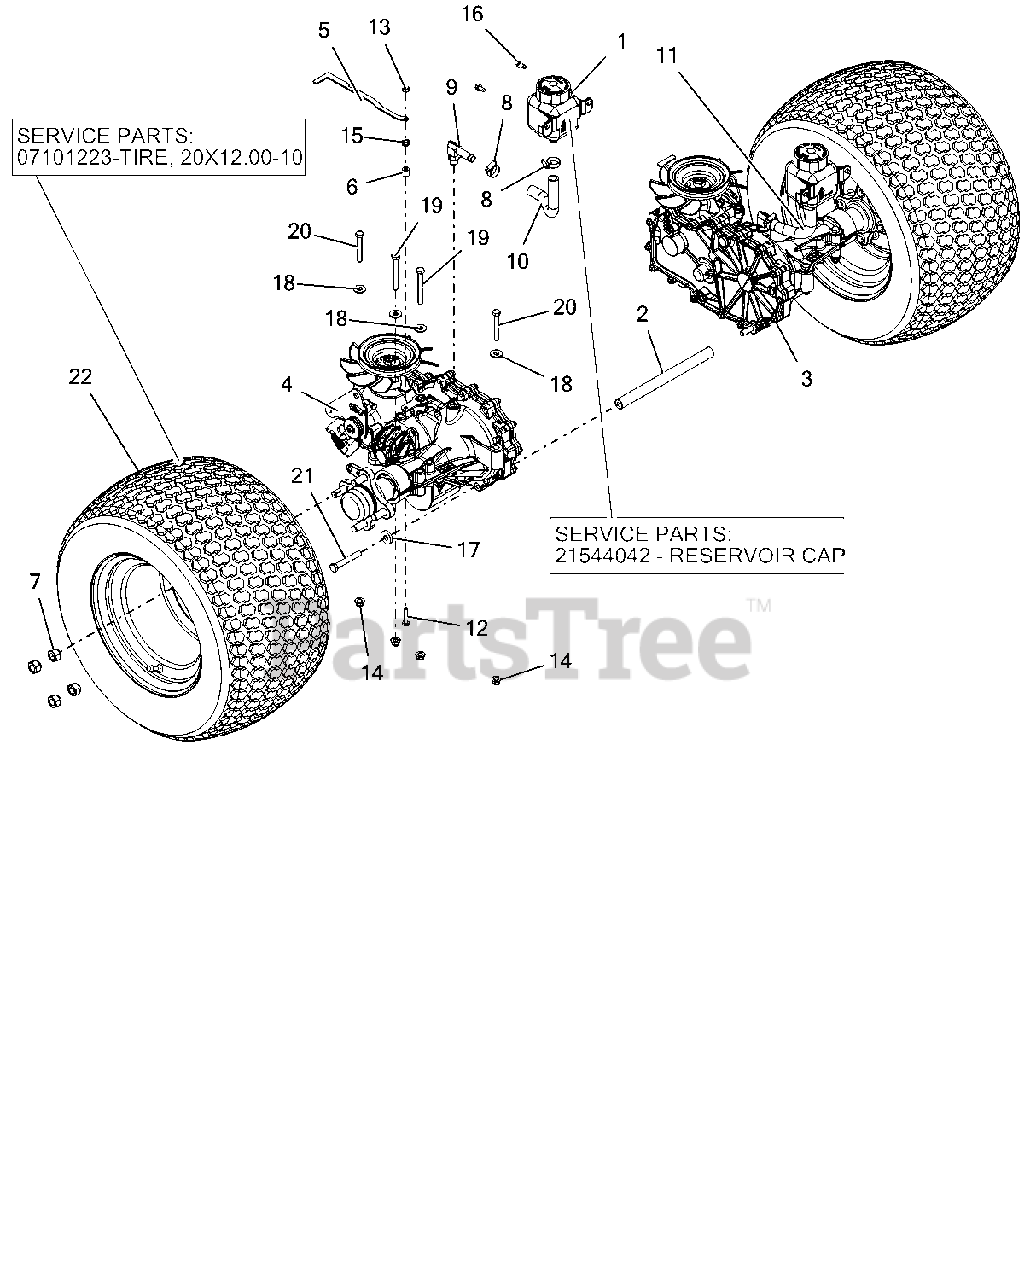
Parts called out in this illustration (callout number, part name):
1	TANK, EXPANSION ZT2800
1	RESERVIOR CAP
2	ROD, TRANSAXLE BRACE-9.27 (BLACK)
3	TRANSAXLE, ZT2800 - LH
4	TRANSAXLE, ZT2800 - RH
5	BRKT, VALVE DUMP -XL
6	BSHG, SLV .265X.500X.500
7	NUT, LUG .500-13
8	CLAMP, .88 DIA HOSE
9	FITTING, HYD (90 DEG)
10	HOSE, EXPANSION TANK-FORMED RH
11	HOSE, EXPANSION TANK-FORMED LH
12	BLT-HEX .25-20X1.25 GR5 YWZC
13	NUT-LK-CTR-JAM .25-20 YWZC
14	NUT-LK-NYL-FLG .31-18 YWZC
15	@NUT-SPNLK-FLG .25-20 YWZC
16	SCR-TAP .25-20X.50 HWH TR YWZ
17	WSHR-FL-STL .406X1.00X.188 YWZC
18	WSHR-FL-STL.38X.875X.083 YWZC
19	BLT-HEX .31-18X2.75 GR5 YWZC
20	BLT-HEX .31-18X2.25 GR5 YWZC
21	BLT-HEX .38-16X2.50 GR5 YWZC
22	TIRE, 20X12.00-10
22	ASSM TIRE\WHEEL, 20 X 12.00 - 10
